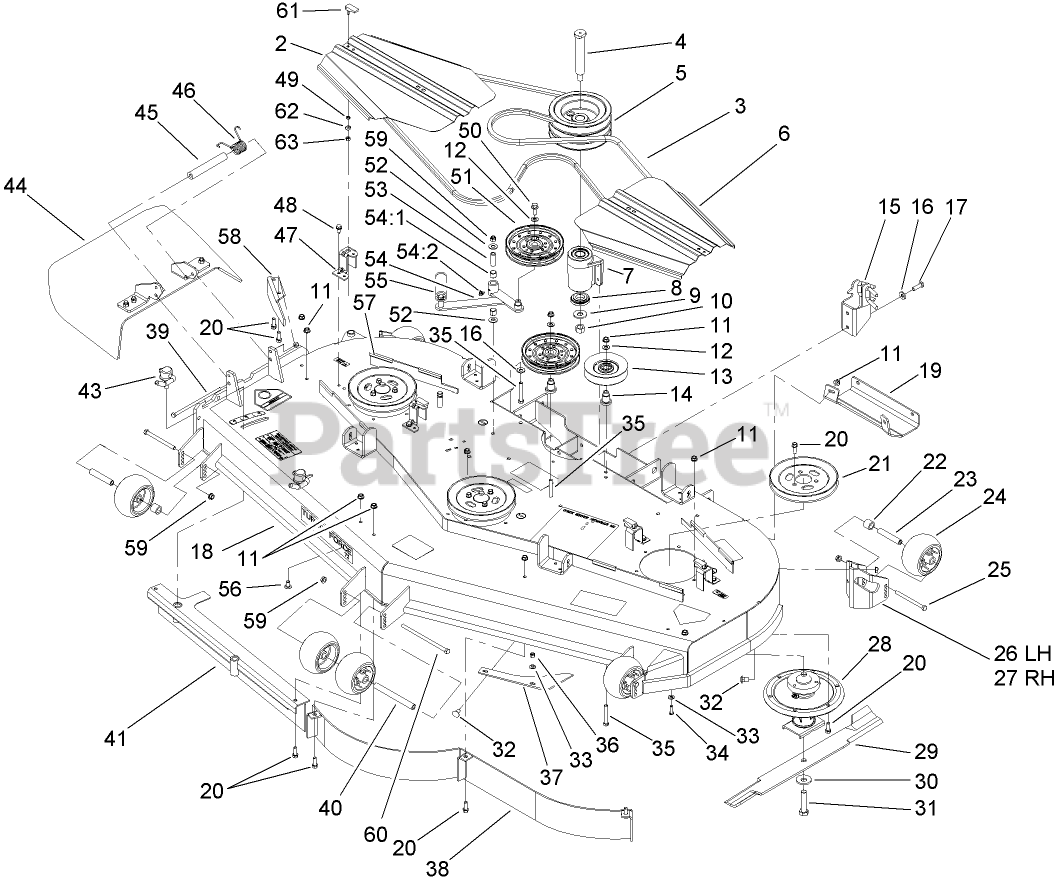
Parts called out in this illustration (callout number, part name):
2	COVER-BELT
3	BELT-V
4	JACKSHAFT
5	SHEAVE-JACKSHAFT
6	COVER-BELT
7	JACKSHAFT ASM
8	SPACER-GUARD, BOTTOM
9	WASHER-SPRING
10	NUT-HEX
11	NUT-HHF, WHIZ
12	WASHER-FLAT
13	PULLEY-IDLER
14	MOUNT-PULLEY
15	GUARD-JACKSHAFT
16	WASHER-BELLEVILLE
17	SCREW-HH
18	DECK ASM
19	Plate-Skid
20	SCREW-HWH
21	PULLEY
22	TUBE-SPACER
23	TUBE-SPANNER
24	ROLLER-SCALP, ANTI
25	SCREW-HH
26	MOUNT-WHEEL, LH
27	MOUNT-WHEEL, RH
28	SPINDLE ASM
29	BLADE-HI FLOW, 24.5 INCH
30	Washer-Blade Bolt, Heavy
31	Screw-Cap
32	SCREW-CARR
33	WASHER-SPRING
34	SCREW-HSBH
35	SCREW-HH
36	NUT-LOCK, NI
37	PLATE-TURBO
39	SCREW-HH
40	SPACER-WHEEL
43	LEVER ASM
44	RUBBER DEFLECTOR ASM
45	SPACER
46	SPRING-TORSION
47	BRACKET-COVER
48	SCREW-HWHTF
49	WASHER
50	SCREW-HHF
51	Idler-Flat
52	WASHER-FLAT
53	BUSHING
54	IDLER ARM ASM
54:1	SLEEVE-BEARING
54:2	FITTING-GREASE, 90 DEG
55	SPRING-EXTENSION
56	SCREW-CARR
57	STRIP-SEAL
58	BAFFLE-DISCHARGE
59	NUT-LOCK, NI
60	SCREW-HH
61	HANDLE-LATCH, SWELL
62	BUSHING-LATCH, SWELL
63	NUT-LOCK, HH
